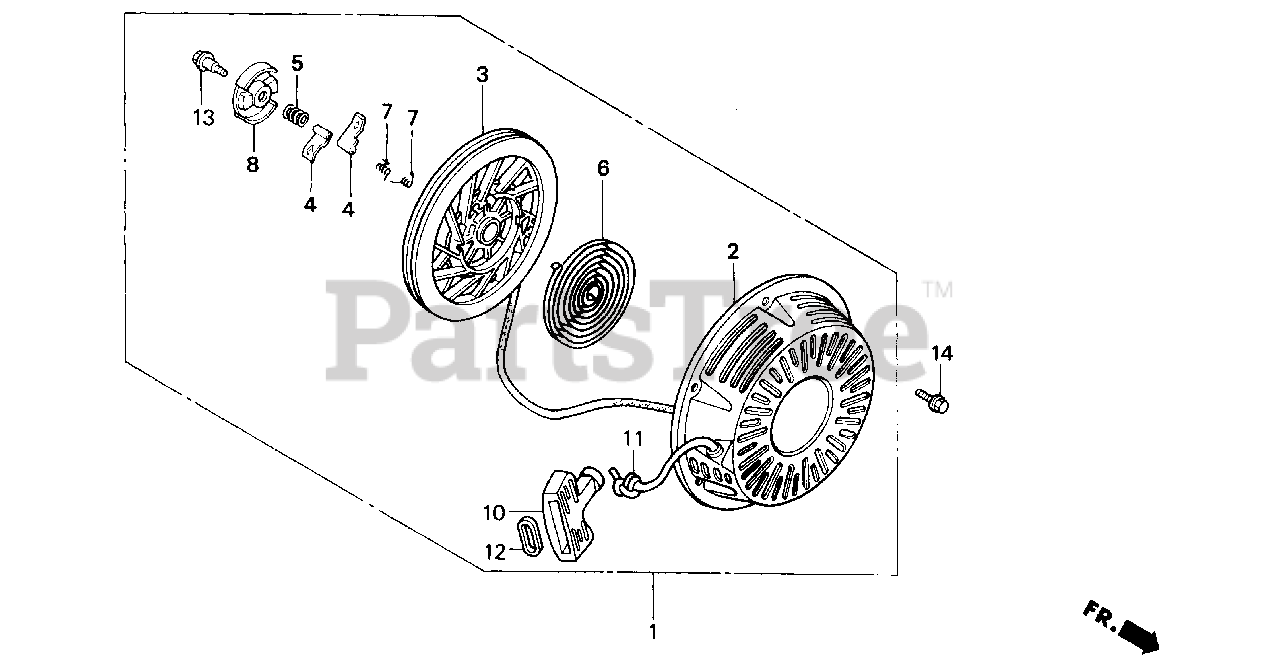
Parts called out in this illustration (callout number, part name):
1	STARTER ASSY., RECOIL *R8* (BRIGHT RED)
2	CASE, RECOIL STARTER *R8* (BRIGHT RED)
3	PULLEY, RECOIL STARTER
4	RATCHET, STARTER
5	SPRING, FRICTION
6	SPRING, STARTER RETURN
7	SPRING, RATCHET
8	RETAINER, SPRING
10	GRIP, STARTER
11	ROPE, RECOIL STARTER (N/A: USE P/N 08560-ZG921-11)
12	GRIP, REINFORCEMENT
13	SCREW, CENTER
14	BOLT, FLANGE (6X8)
